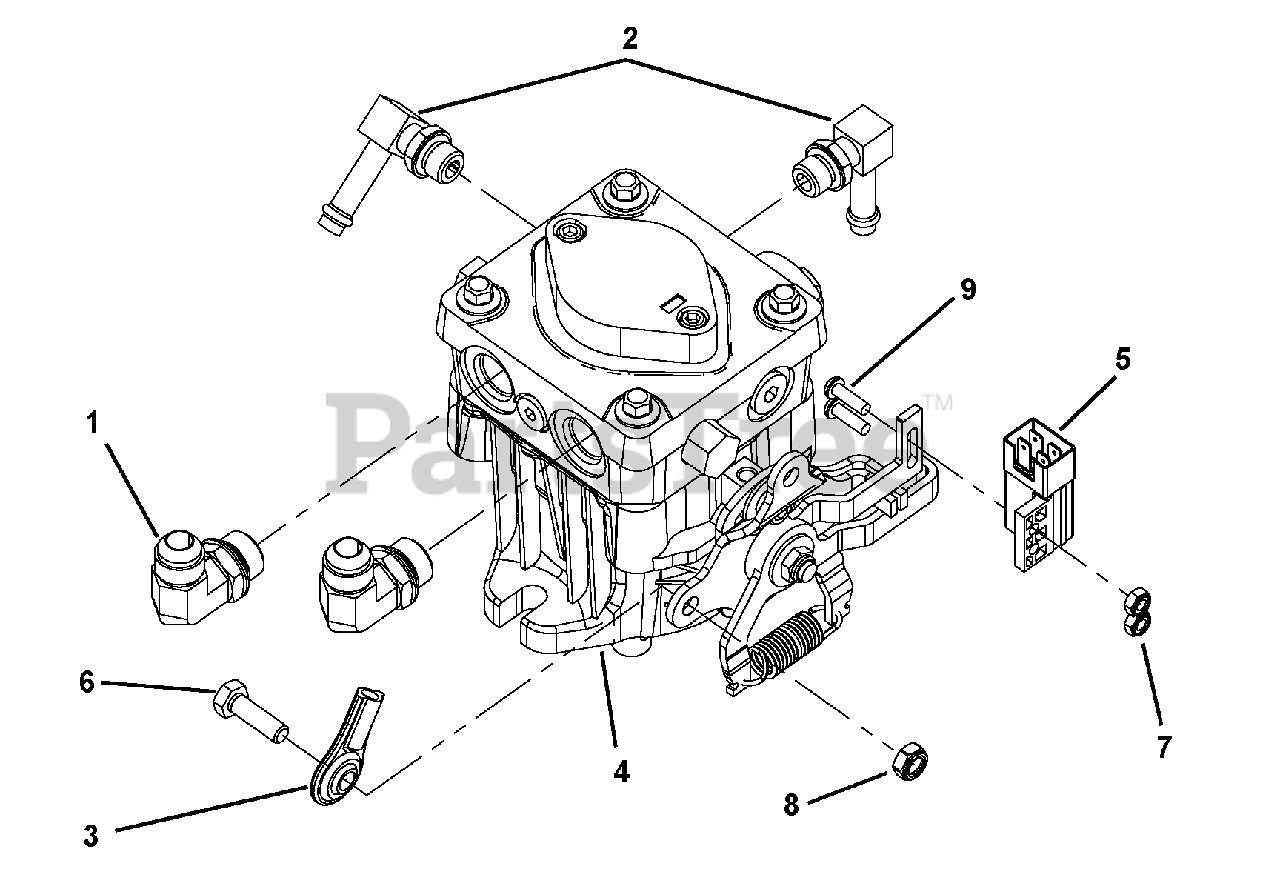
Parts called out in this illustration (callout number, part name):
1	Fitting, Includes O-Ring
2	Fitting -Adaptor .562-18 Steel Thread
3	Rod End, 5/16 RH -Female
4	Pump, Left Hand
5	Switch, Plunger Diametral Pitch -N.O. -N.C.
6	Bolt, Hex .31 x 1.00 Grade 5
7	Nut, Locking, Nylon 10-24 w/Insert
8	Nut, Locking, Nylon .312-18
9	Screw, Machine 10-24 x .62 P/HD
NS	Pump Seal Kit
